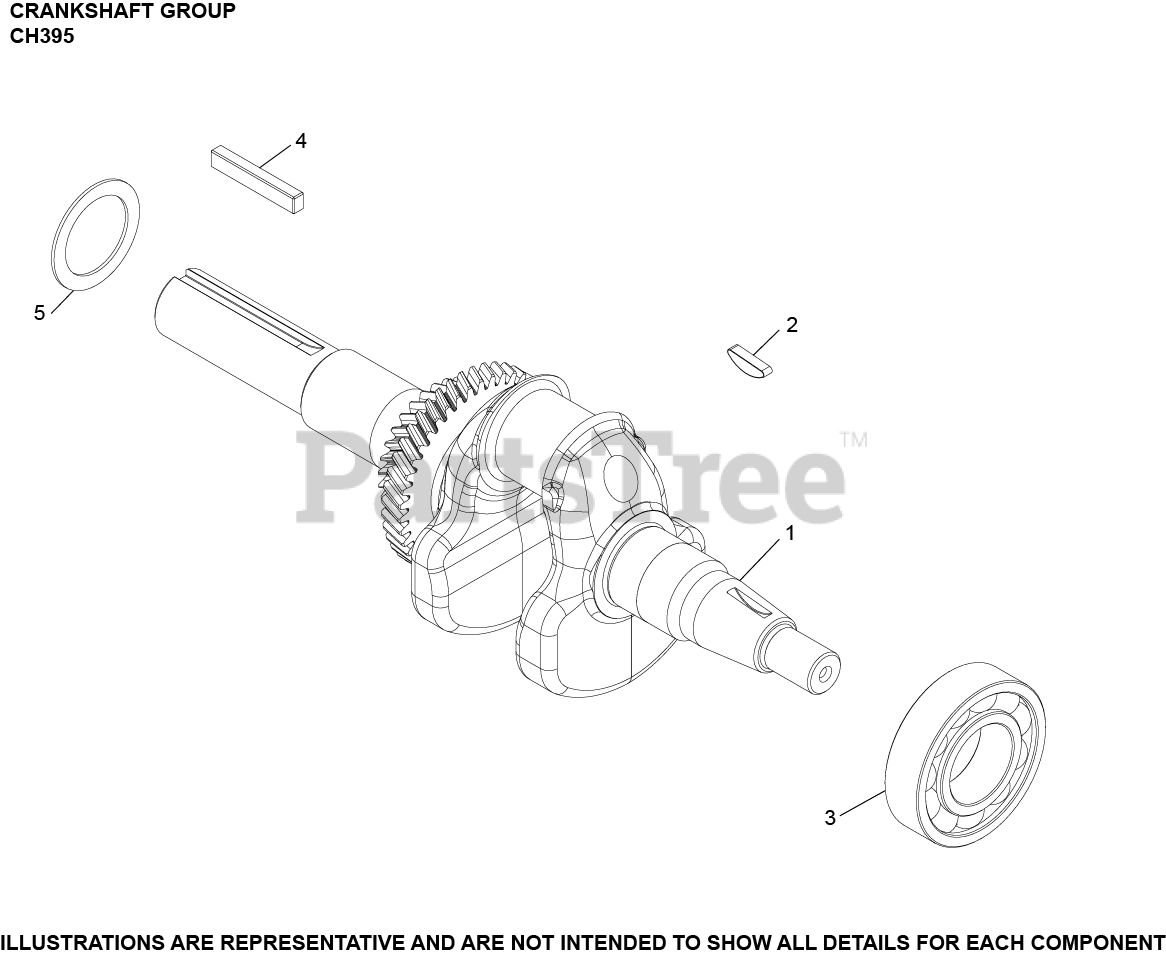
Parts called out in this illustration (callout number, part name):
1	CRANKSHAFT ASSEMBLY
2	KEY, FLYWHEEL
3	BEARING, CRANKSHAFT
5	KIT, SHIMS
